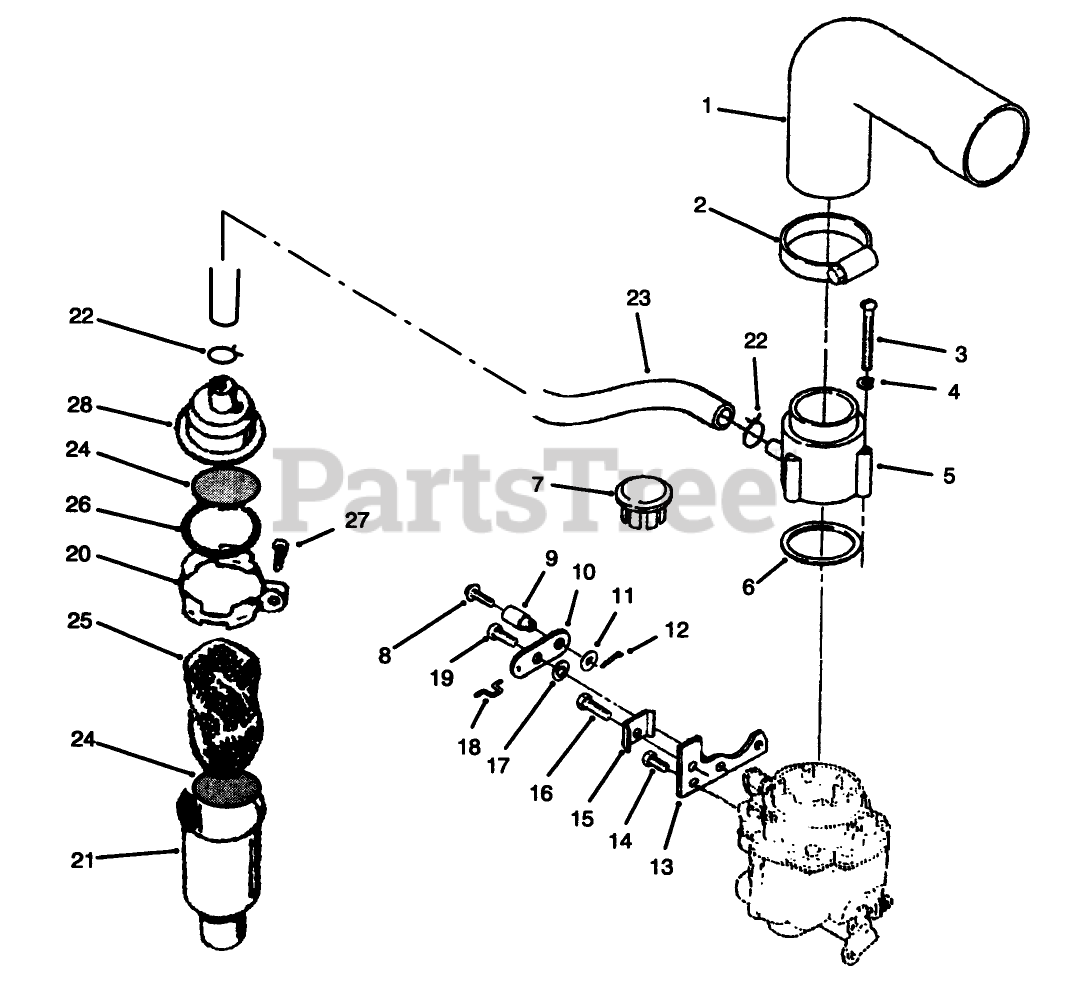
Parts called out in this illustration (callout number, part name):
1	INLET ASM
2	HOSE CLAMP
3	RD HD MACH SCREW
4	WASHER-LOCK
5	ADAPTER
7	PLUG, HOLE
8	SCREW
9	SWIVEL
10	SWIVEL-CHOKE
11	WIRE CLAMP
12	PIN-COTTER
13	BRACKET
14	SCREW-HWH
16	SCREW-TAPPING
17	WASHER-LOCK, INT
18	LINK-CHOKE
19	BOLT-SHOULDER
20	Clamp
21	TUBE-BREATHER
22	CLAMP
23	BREATHER HOSE
24	SCREEN-BREATHER TUBE
25	FILTER
26	SEAL - O-RING
27	SCREW-TAPPING, ROUND HEAD
28	BREATHER-CAP AND VALVE
